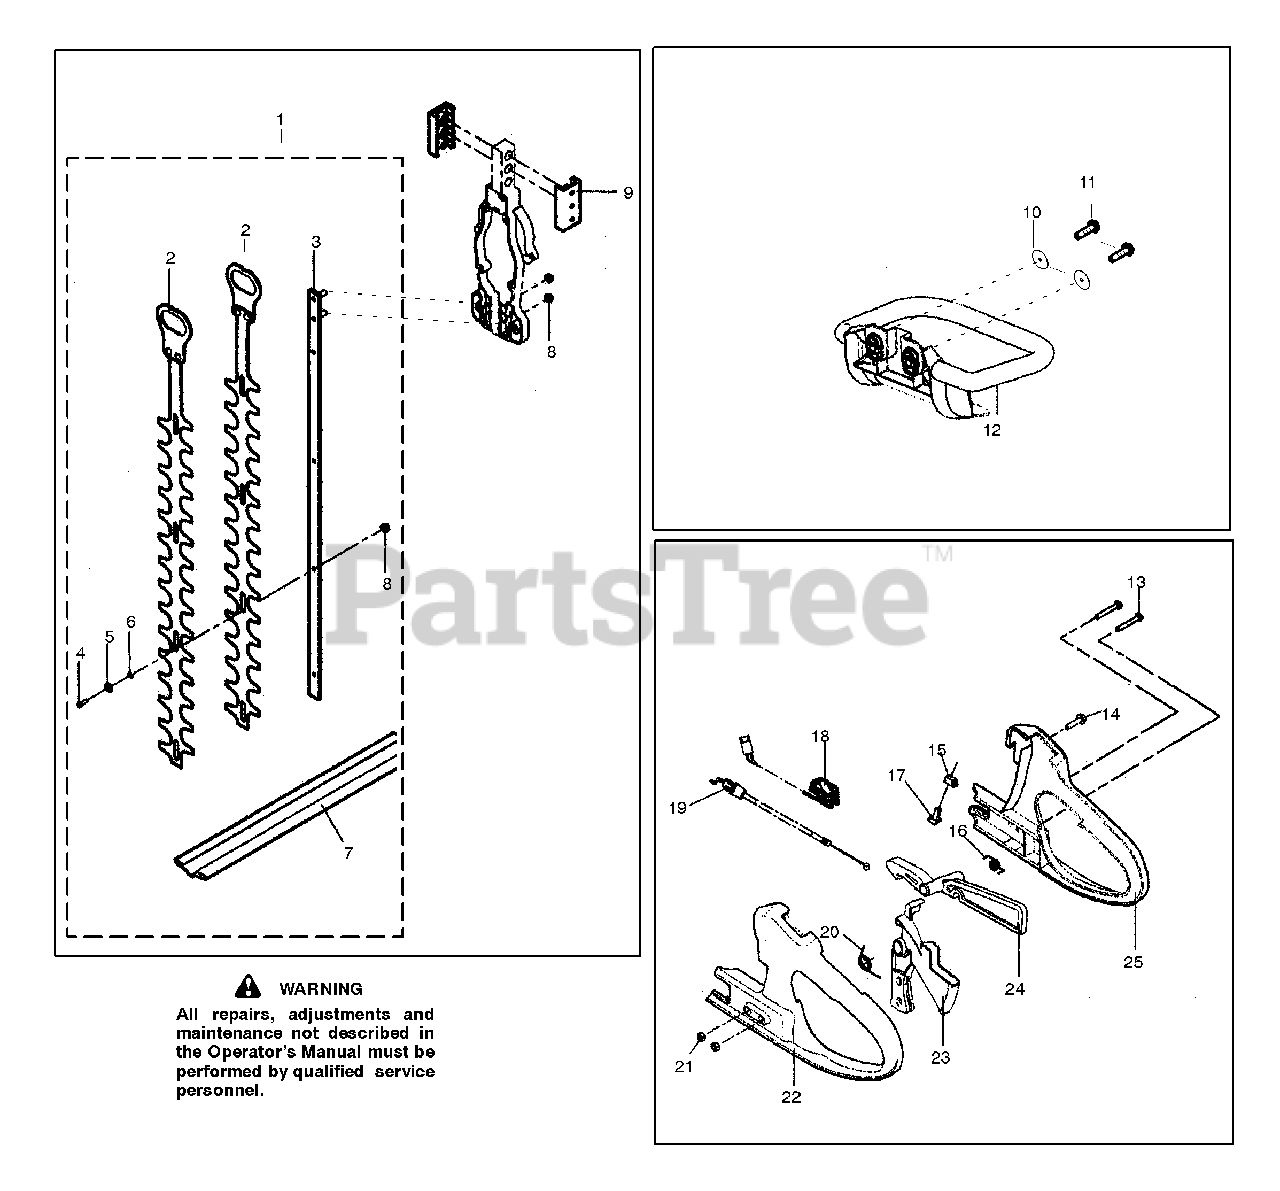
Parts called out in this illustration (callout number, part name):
1	Kit-Assy-Blade
2	Cutter B
3	Cutter guide
4	Step Bolt
5	Conical Spring Washer
6	Cutter Washer
7	Sleeve-Blade
8	U-Hexagon Nut Flange
9	Absorber
12	Handle-Front
13	Socket Screw
14	Tapping Screw
17	Half Gas Lever
18	Stop Switch Assy.
19	Throttle Wire
21	U-Hexagon Nut
22	Handle-Rear
25	Handle -Rear
